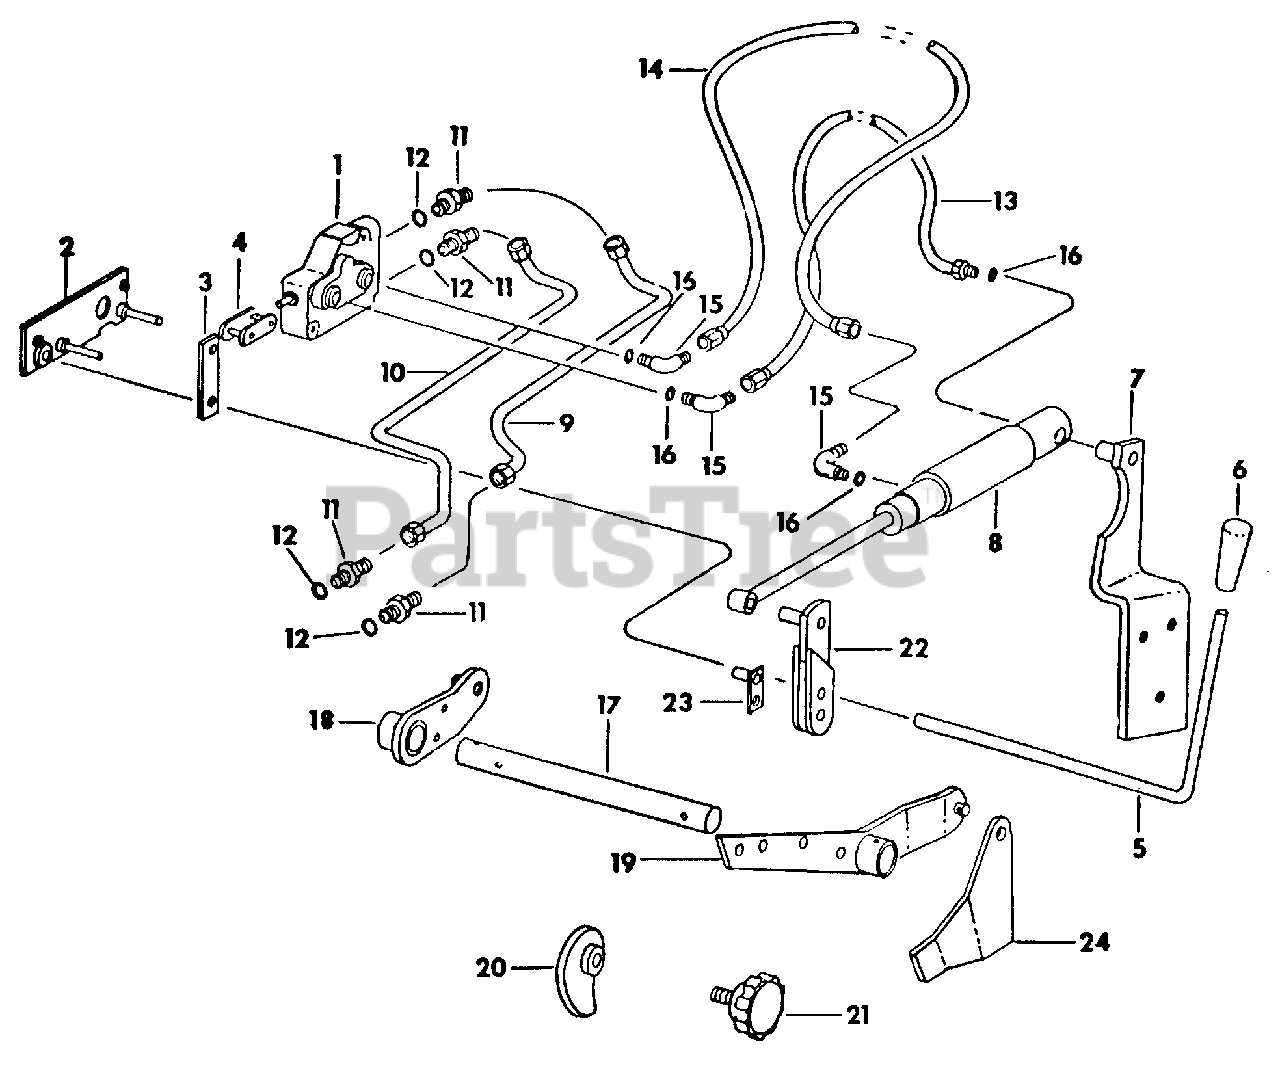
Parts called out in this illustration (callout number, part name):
1	Valve Assy, Control
2	Plate Assy, Valve Mtg
3	Link, Valve Handle
4	Link, Chain
5	Handle, Valve
6	Grip, Handle
7	Bracket Assy, Lift
8	Cylinder, Lift
9	Tube Assy, Return
10	Tube Assy, Pressure
11	Union, 37 Deg Flared Short Swivel Tube
12	O-Ring, 3/8 OD Tube
15	Elbow, 90 Deg Tube
16	O-Ring, 3/8 OD Tube
18	Arm Assy, Lift LH
19	Arm Assy, Lift RH
20	Cam Assy, Lift Handle Stop
21	Knob, Torque
22	Clevis Assy, Hyd Lift
23	Pin Assy, Float Lockout
24	Plate Assy, Rockshaft
